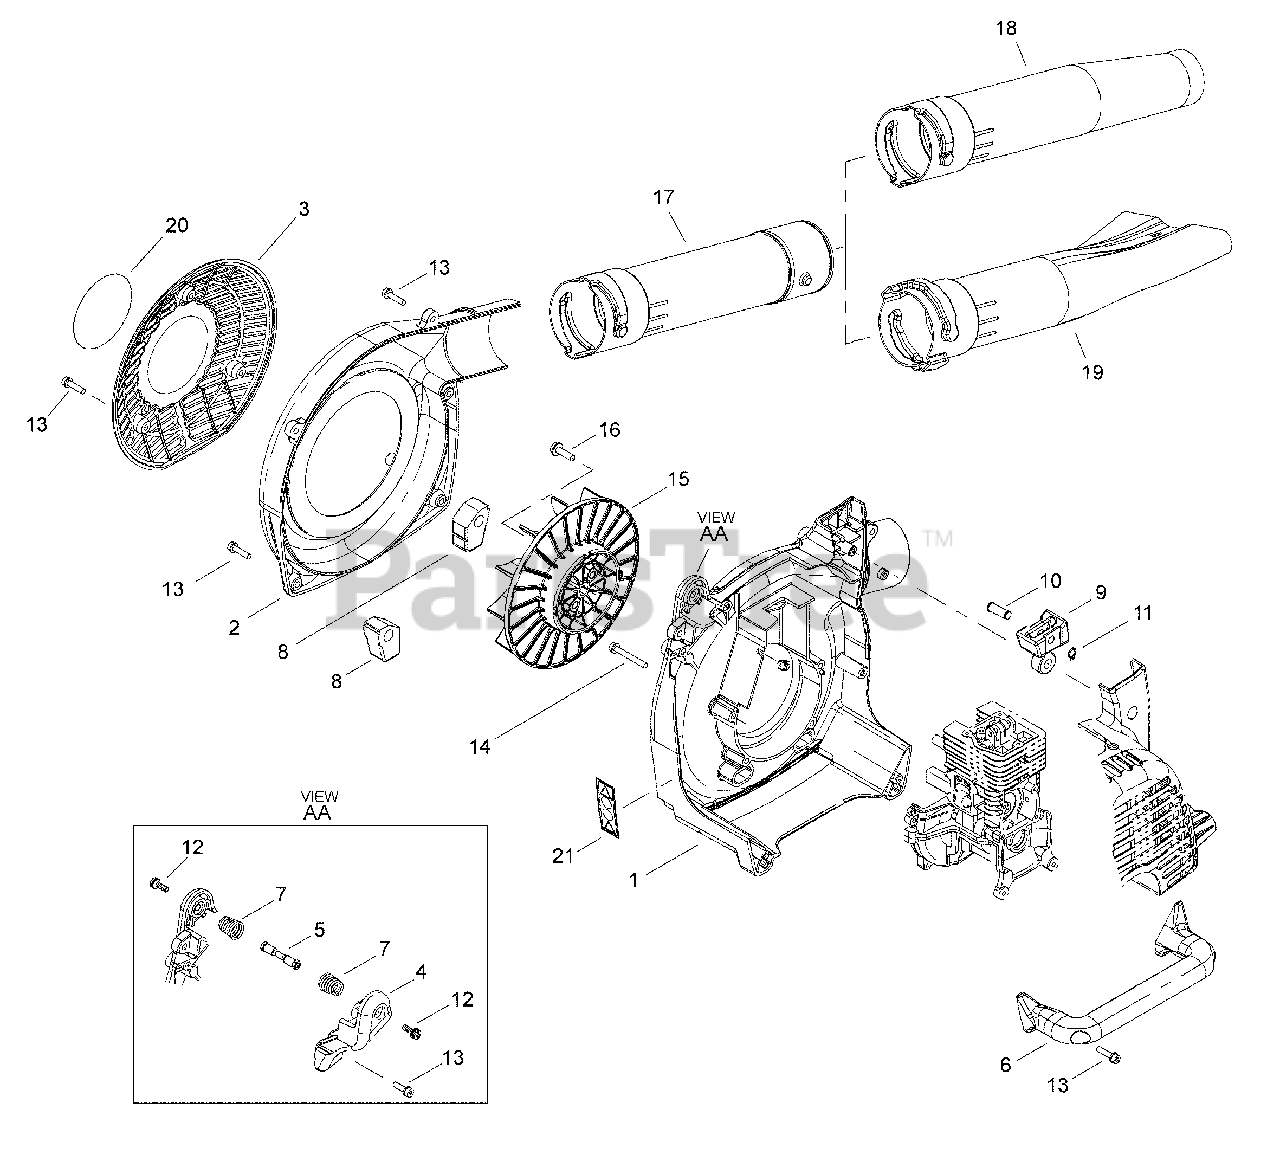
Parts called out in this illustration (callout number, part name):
1	COVER, FAN - RIGHT
2	COVER, FAN - LEFT
3	COVER, INTAKE
4	COVER, HANDLE
5	NUT
6	HANDLE - LOWER
7	SPRING
8	CUSHION - REAR
9	CUSHION - REAR
10	PIN - LOCKING
11	RING, RETAINING - 8
12	SCREW - 5X16
13	BOLT - 5X20
14	SCREW - 5X40
15	FAN
16	SCREW - 6X20
17	TUBE, BLOWER
18	NOZZLE
19	FAN TIP NOZZLE
20	LABEL - MODEL EB2510
21	LABEL - CAUTION
